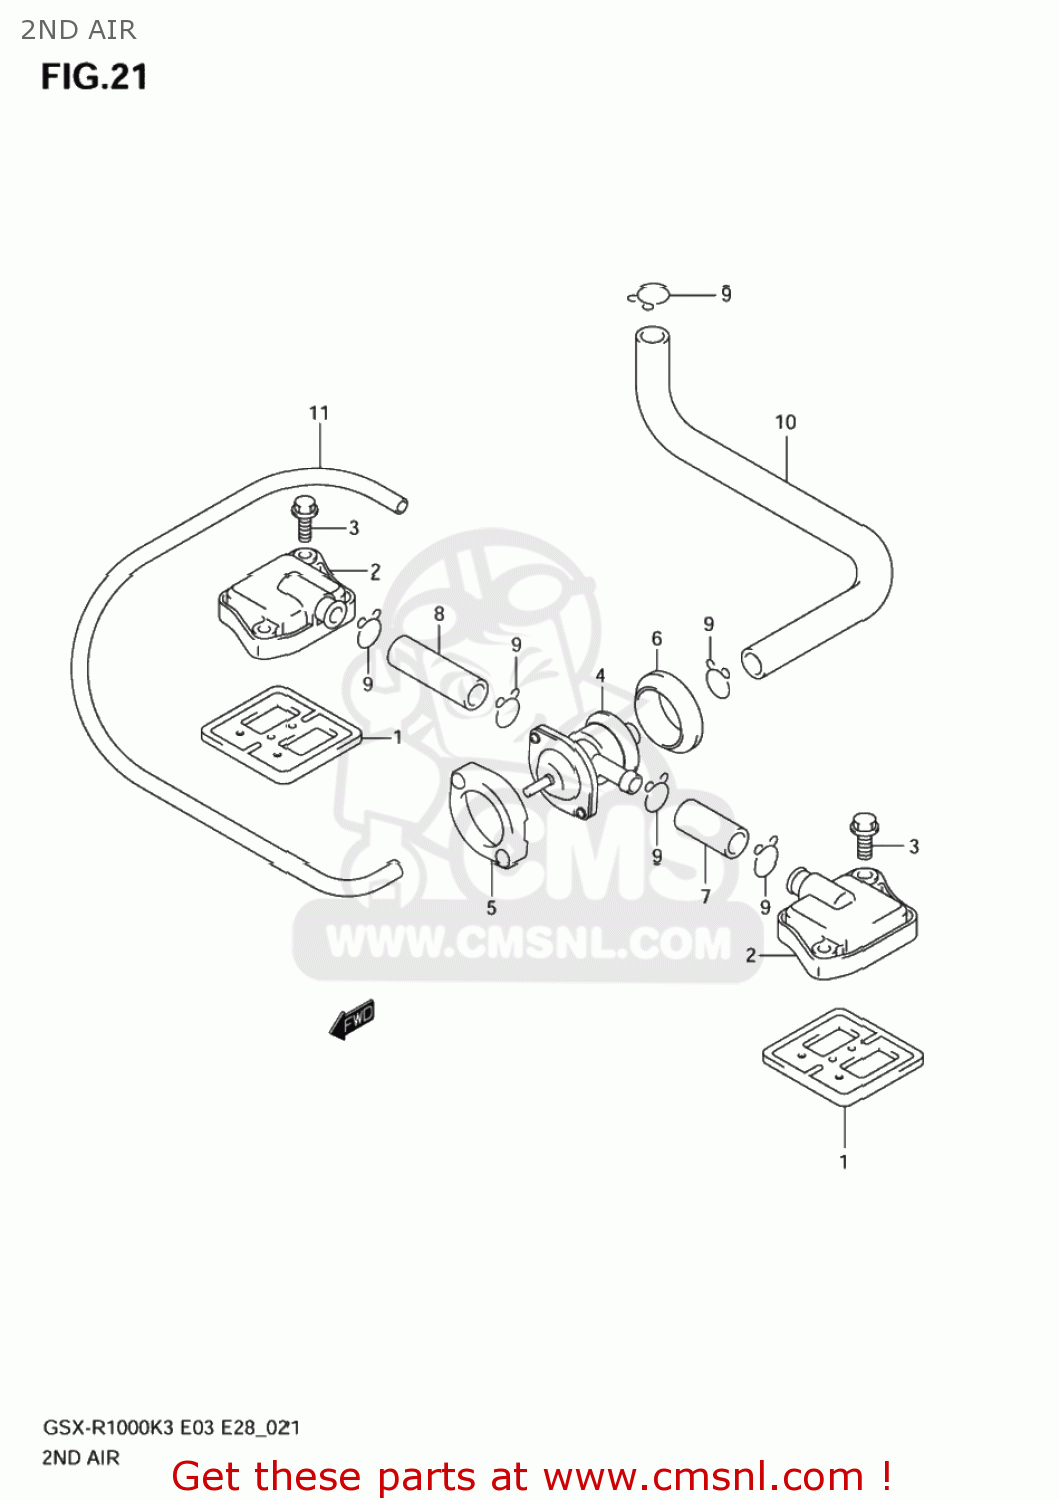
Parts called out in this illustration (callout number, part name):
1	VALVE ASSY,2ND
2	COVER,2ND AIR REED VALVE
3	BOLT,SECOND AIR REED VALVE
4	VALVE ASSY,AIR CUT
5	CUSHION,AIR CUT VALVE UPR
6	CUSHION,AIR CUT VALVE LWR
7	HOSE(11X16X600)
8	HOSE(11X16X600)
9	CLIP
10	HOSE,2ND AIR CLEANER
11	HOSE(3.5X7.5X600)
